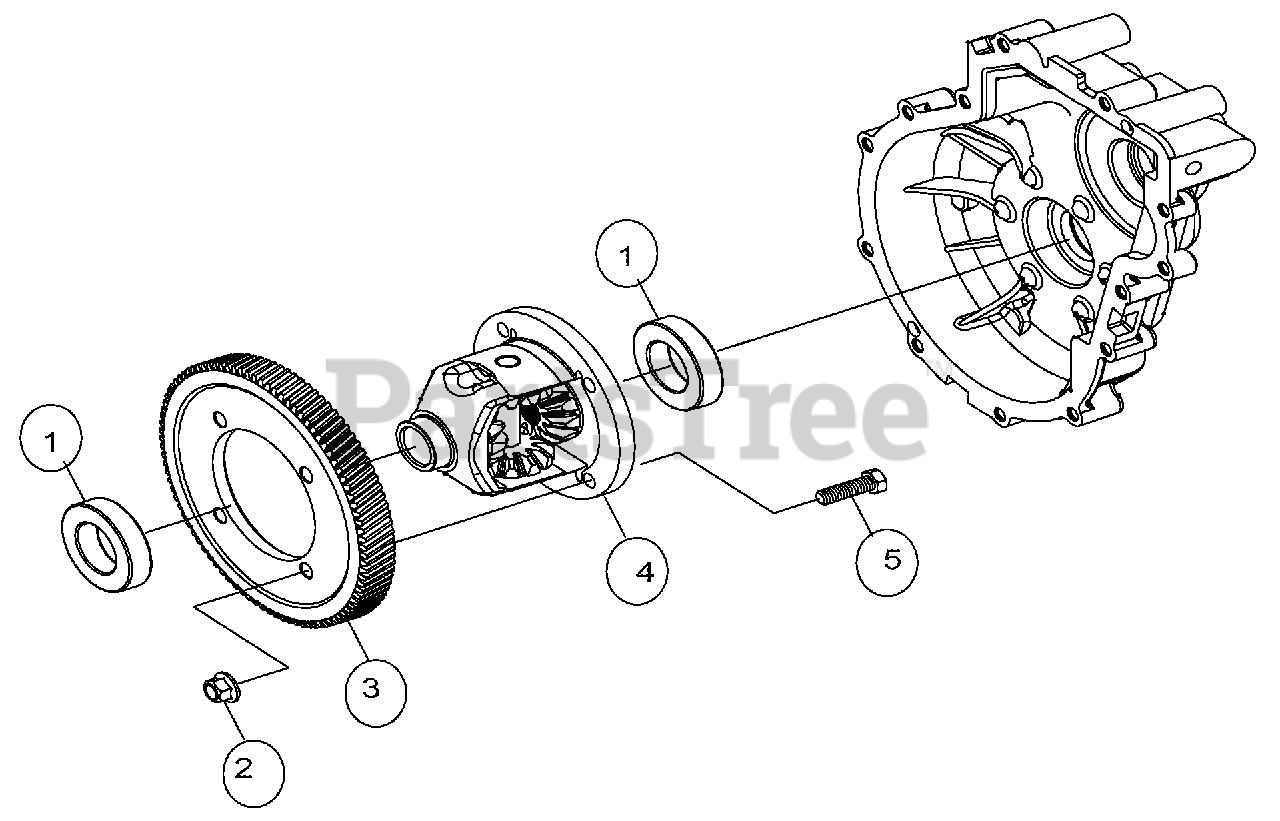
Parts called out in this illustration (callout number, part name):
1	Bearing, Ball
3	Gear, Helical (Ring)
4	Assembly, Differential
